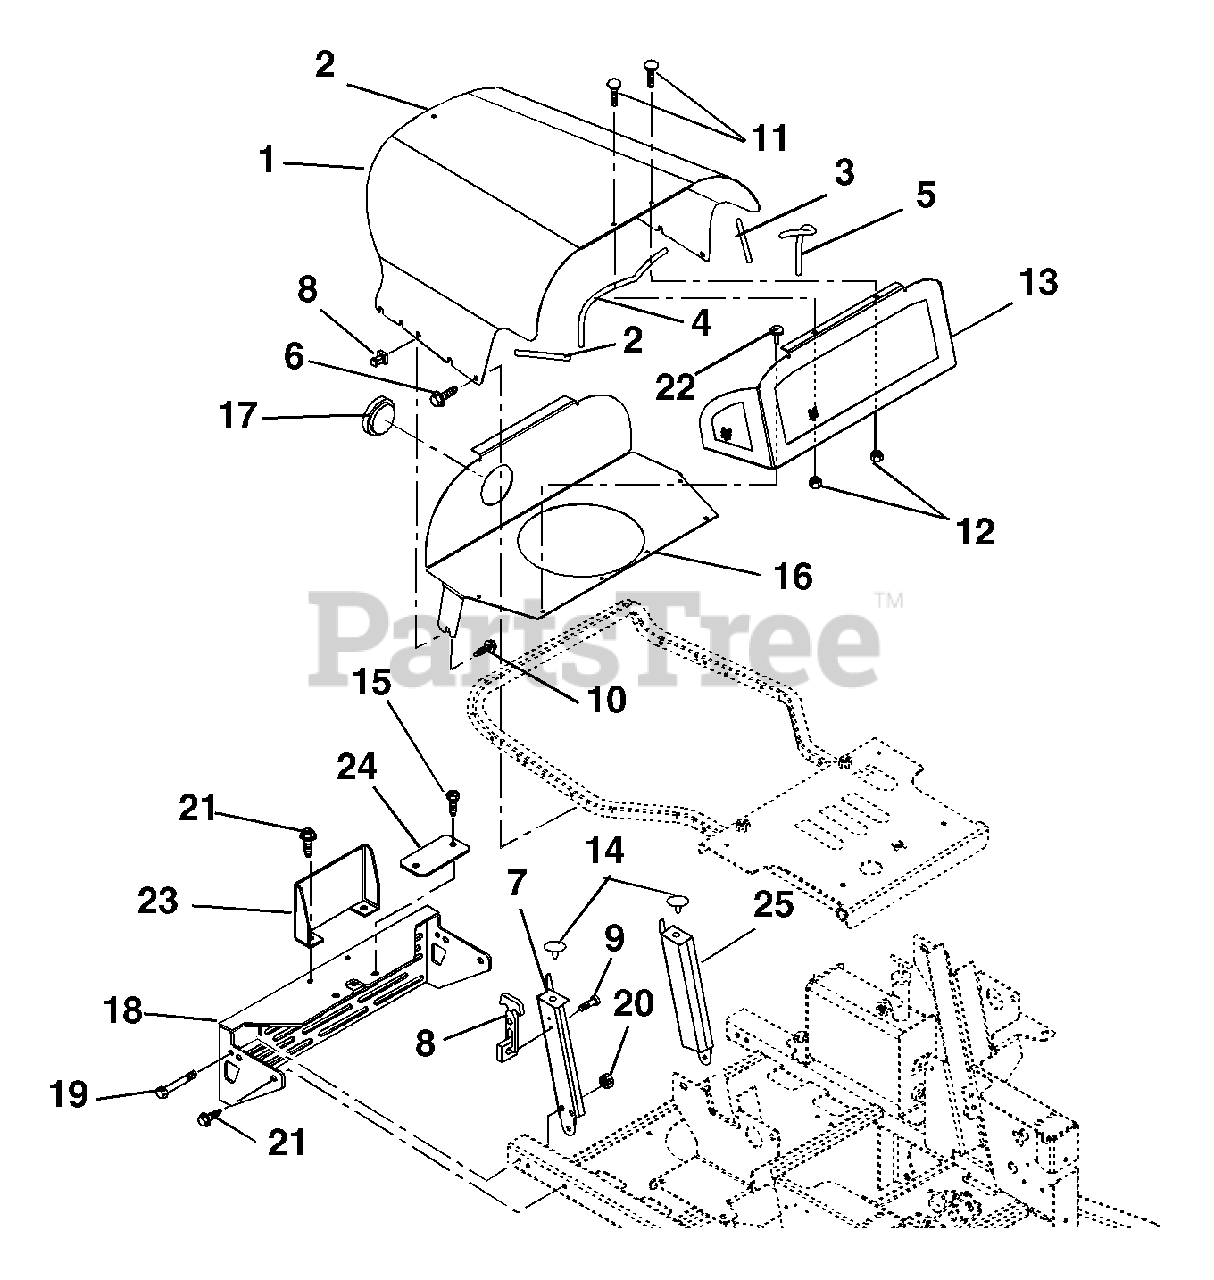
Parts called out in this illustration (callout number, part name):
2	Seal-Trim-Lok Bulk .06 Bubble
3	Seal-Trim-Lok Bulk .06 Bubble
4	Seal-Trim-Lok Bulk .06 Bubble
5	Seal-Trim-Lok Bulk .06 Bubble
6	Screw-Tapping .38-16 x .50 Hex Washer Head
7	Hood Support Right-Hand
8	Latch-Rubber
9	Screw-Machine 10-24 x .50 Hex Washer Head
10	Screw Machine 10-24 x .50 Hex Washer Head
11	Bolt-Round Head Square Shank .25-20 x .50 Grade 5
12	Nut-Locking-Nylon .25-20
13	Weldment, Plenum
14	Button Bumper
15	Screw-Tapping .250-20 x .37 Hex Washer Head (020)
16	Back, Plenum
17	Plug, Hole-3.38 (032, 033)
18	Bumper-Rear
19	Bolt-Hex .38-16 x 2.75 Grade 5
20	Nut-Locking-Center .38-16
21	Screw-Tapping .38-16 x .75 Hex Washer Head (020)
21	Screw-Tapping .38-16 x .75 Hex Washer Head (029, 030, 032, 033, 034, 035)
22	Rivet-Pop .18 x .402
23	Guard, Muffler (029, 030, 032, 033, 034, 035)
24	Plate, Bumper (020)
25	Weldment, Hood Support-Left Hand
